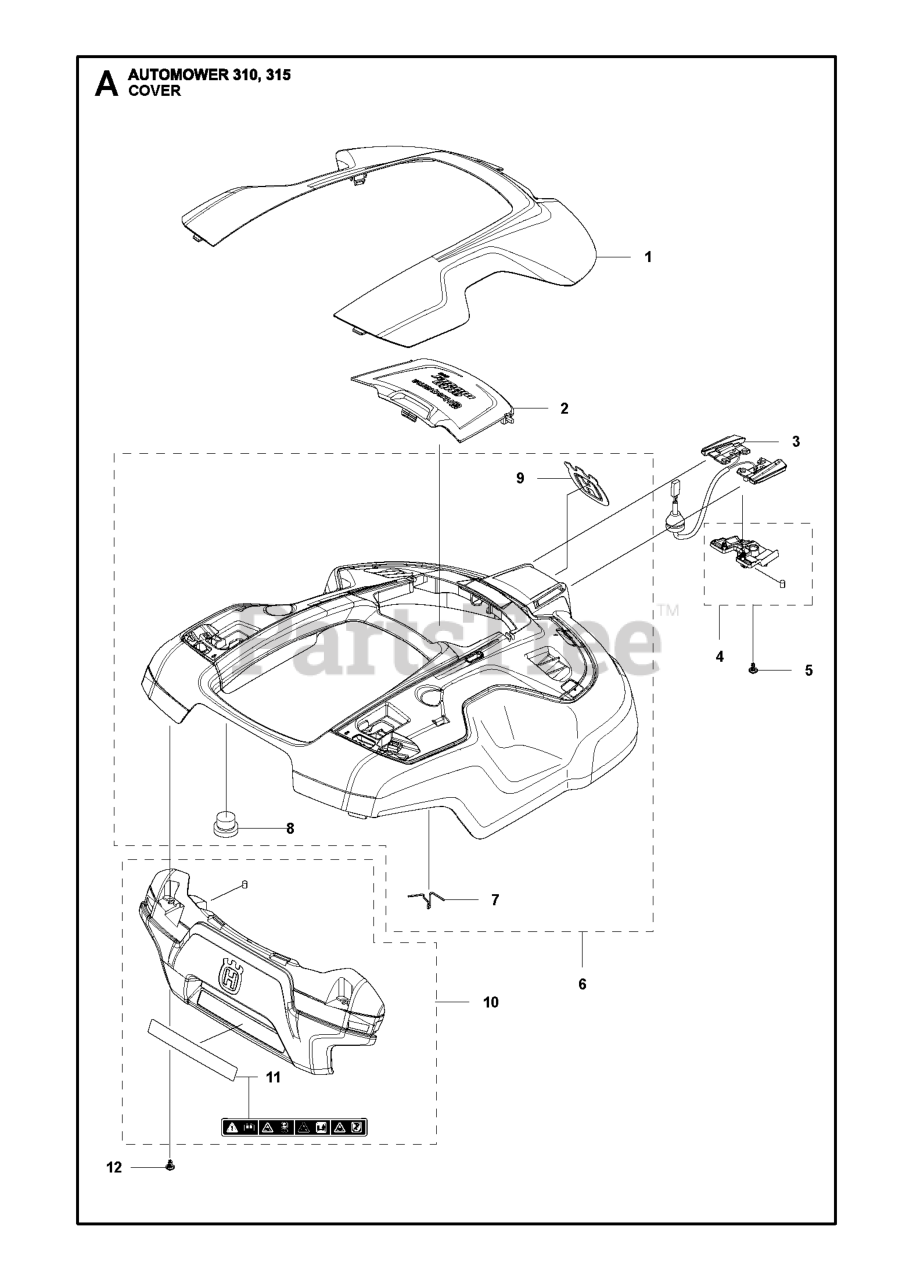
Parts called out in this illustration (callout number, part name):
1	ORANGE COVER
1	GREY COVER
1	WHITE COVER
2	HOOD 310
3	LOOM CHARGING PLATE
4	HOLDER KIT
5	SCREW ITXPANT
7	SPRING HOOD
8	CAP SNAPLOC
9	DECAL HUSQVARNA CROWN HEIGHT 5
10	BUMPER KIT
11	LABEL WARNING P15
12	SCREW ITXPANT
